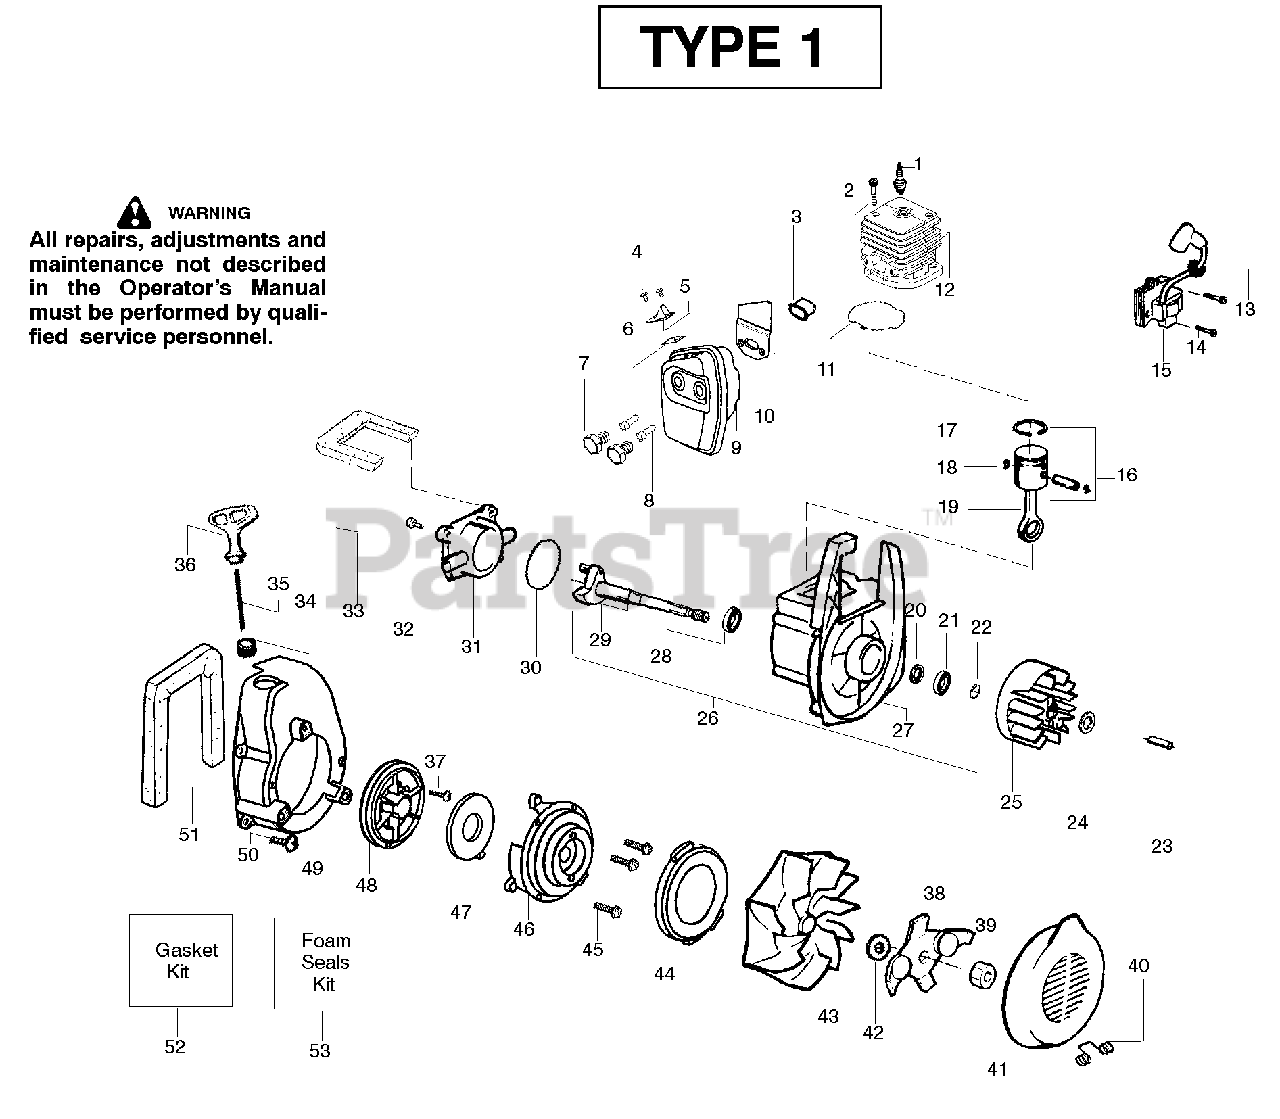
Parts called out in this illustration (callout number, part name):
1	Spark Plug (RCJ-6Y)
3	Insulator-Heat
5	Deflector-Muffler
6	Kit-Spark Screen
7	Bolt-Muffler-external
8	Screw-Muffler-Internal
9	Kit-Muffler
10	Gasket-Baffle (kit)
11	Gasket-Cylinder (kit)
12	Kit-Cylinder
13	Grommet-Ign. Module
14	Screw-Ignition Module
15	Ignition Module
16	Kit-Piston
17	Piston Ring
18	Retainer-Piston Pin
19	Assy-Connecting Rod
20	Seal-Crankcase
21	Bearing-Outer
22	Retainer Ring-C'chaft
23	Spacer-Flywheel
25	Assy-Flywheel
26	Assy-Crankcase/Crank shaft
27	Assy-Crankcase
28	Bearing-Inner
29	Assy-Crankshaft
30	O-ring-C/case (kit)
31	Cover-Crankcase
32	Screw
33	Foam-219mm (kit)
34	Eyelet-Flange
35	Kit-Rope
36	Handle-Starter
37	Screw-Rope
38	Assy-Mulch Blade
40	Spring-Return Cover
41	Inlet Door
42	Washer-Belleville
43	Assy-Impeller
44	Seal-Ring
46	Housing-Pulley
47	Spring-Starter
48	Kit-Starter Pulley
49	Fan Housing
50	Screw
51	Foam-365mm (kit)
52	Kit-Gasket
53	Kit-Foam Seals
